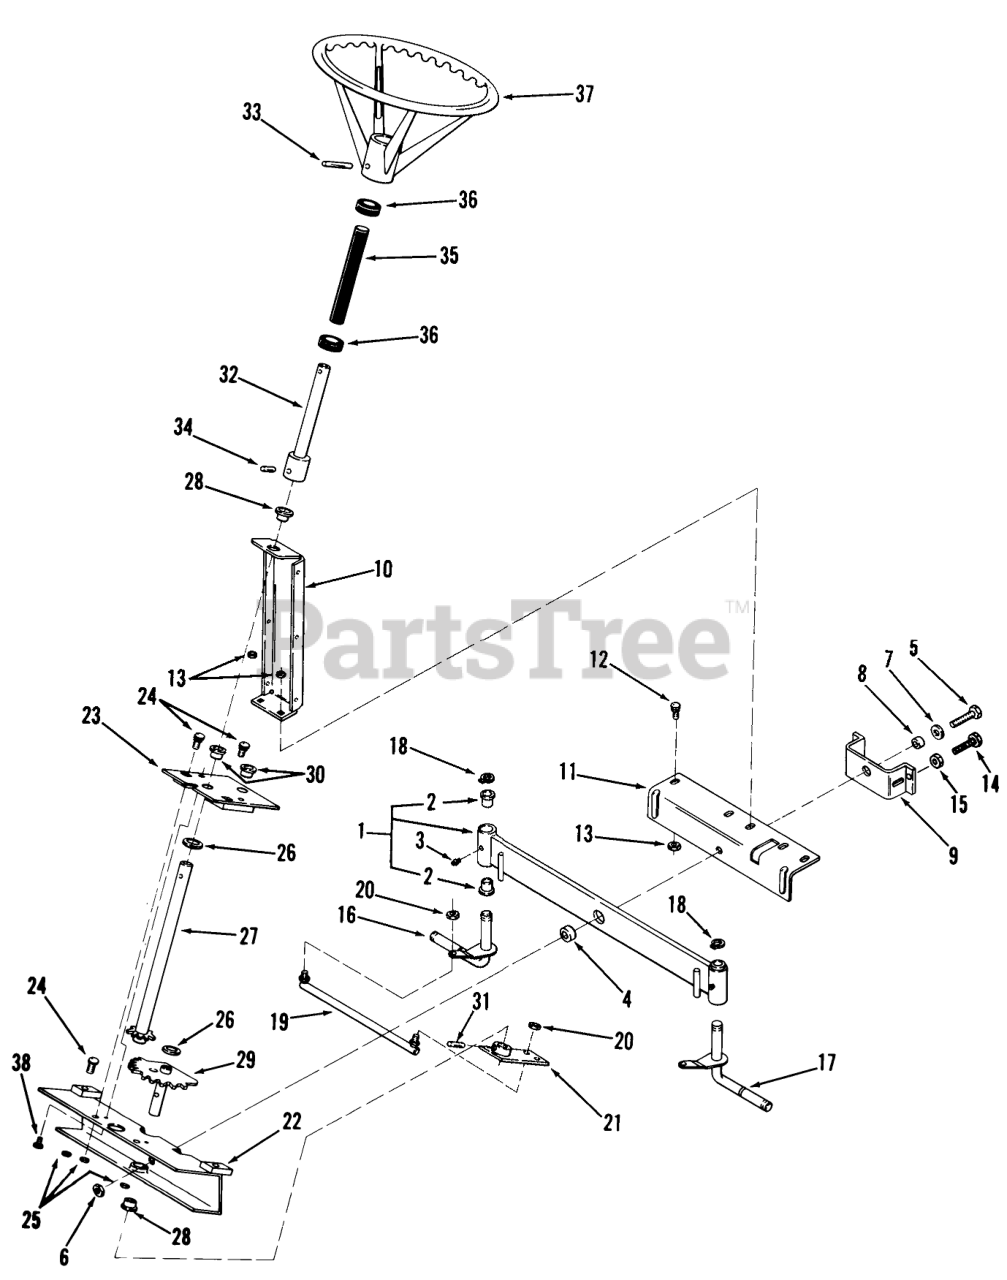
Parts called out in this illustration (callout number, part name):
2	BUSHING
19	ASSY-BALL JOINT *R
28	BEARING
29	ASSY-STEERING SEC *R (NS)
30	BUSHING
34	SPIROL PIN
38	Bolt
